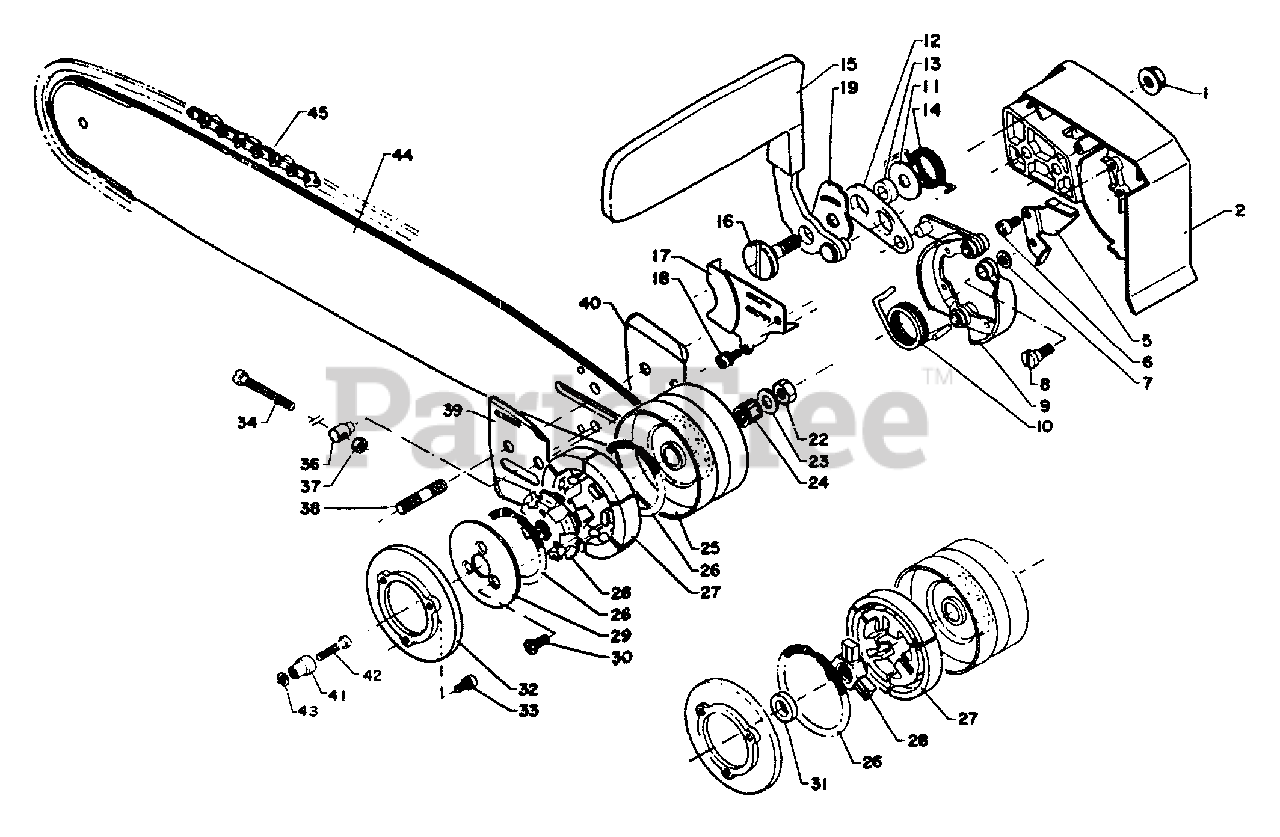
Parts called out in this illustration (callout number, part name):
1	NUT - FLANGE
2	COVER, GUIDE BAR
5	GUIDE, BRAKE SHOE
6	SCREW - 5X8
7	WASHER - 4
9	SHOE, BRAKE
10	SPRING, BRAKE
11	SPACER
12	CONNECTOR
13	SPACER
14	SPRING, RETURN
15	HANDLE, BRAKE
17	SEAL, DUST
18	SCREW - 4X10
19	WASHER
22	LOCKNUT
23	WASHER
24	BEARING, NEEDLE
25	DRUM, CLUTCH
26	SPRING, CLUTCH
27	SHOE, CLUTCH
28	HUB, CLUTCH
29	PLATE, CLUTCH
30	SCREW - 5X16
31	WASHER, CLUTCH
32	SEAL, DUST
33	SCREW - 4X10
34	SCREW, TENSIONER
36	TENSIONER, CHAIN
37	LOCKNUT - 5
38	STUD, GUIDE BAR
39	PLATE, GUIDE - INNER
40	PLATE, GUIDE - OUTER
41	CATCHER, CHAIN
42	SCREW - 5X25
43	WASHER - 5
44	GUIDE BAR
45	CHAIN, SAW
